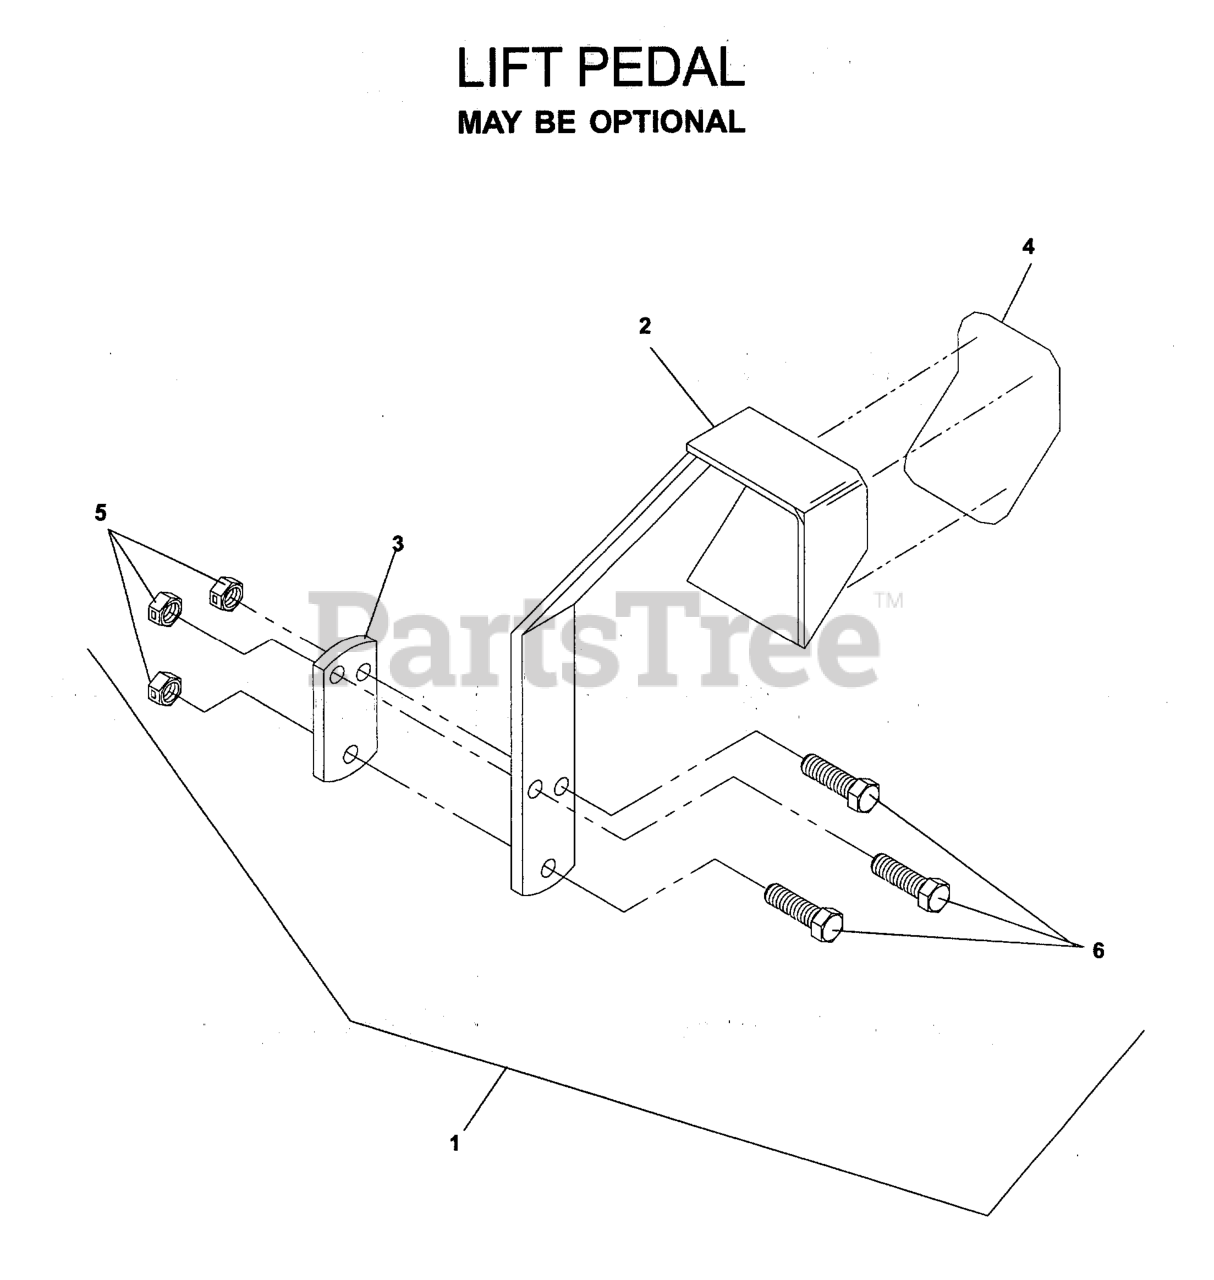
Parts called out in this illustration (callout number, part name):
1	FOOT ASSIST DECK LIFT-GEN II
2	LIFT PEDAL BLK
3	TIGHTENING PLATE BLK
4	ANTI-SKID PAD
5	NUT 3/8-16 NYLOC
6	HCS 3/8C X 1 1/2
